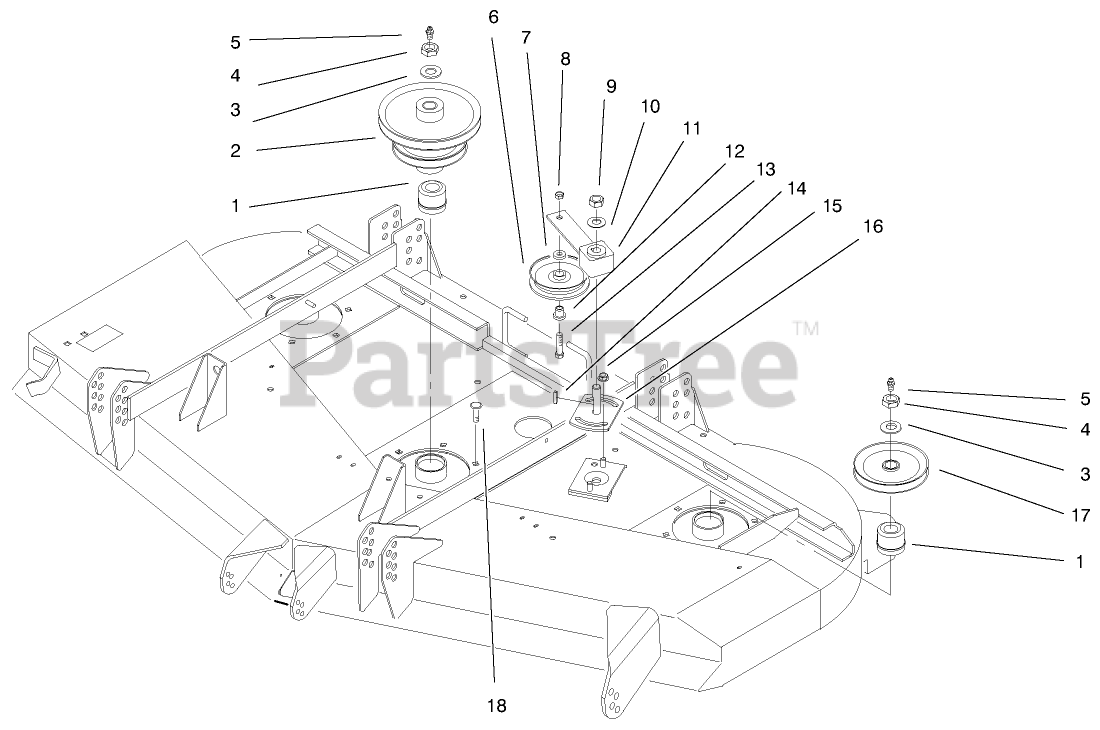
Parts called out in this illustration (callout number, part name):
1	BEARING ASM
2	PULLEY & HUB WA B
3	WASHER
4	NUT-HEX
5	FITTING-GREASE
6	PULLEY-IDLER
7	WASHER-FLAT
8	NUT-HEX
9	NUT-LOCK NI
10	WASHER-FLAT
11	IDLER ARM ASM
12	BUSHING-PULLEY
13	SCREW-HH
14	KEY-SQUARE
15	NUT-HHF, WHIZ
16	PLATE-IDLER, LH
17	PULLEY AND HUB ASM
18	SCREW-CARR
